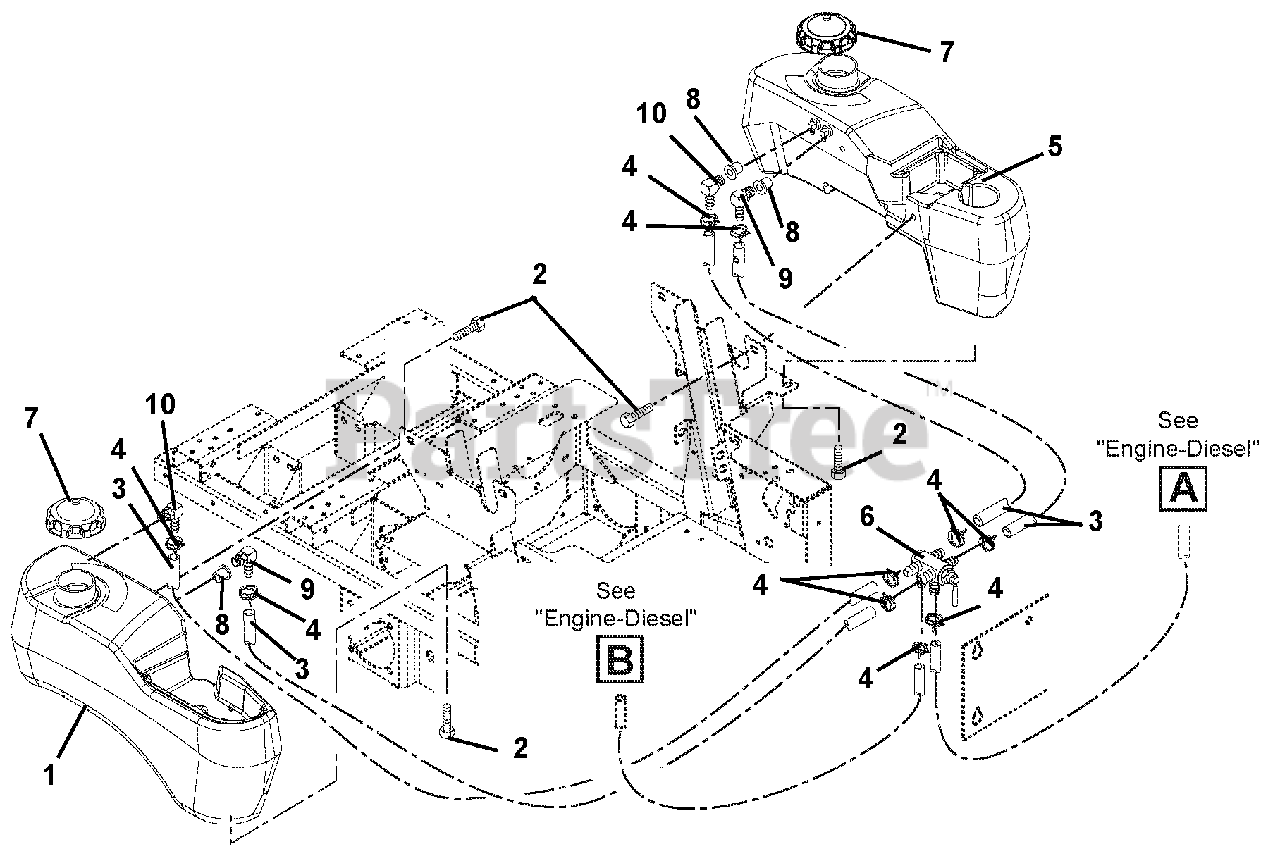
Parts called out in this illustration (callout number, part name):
1	Tank, Fuel-Right Hand
2	Bolt, SEMS .31-18 x .62
3	Hose, .31 ID
4	Clamp, Hose Wire .52/.55
5	Tank, Left Hand Fuel (EYE-Q) 200 Series-EFI
6	Valve, Fuel
7	Cap, Fuel
8	Grommet, Black (Will not replace orange)
9	Fitting, Tank
10	Fitting, Tank
